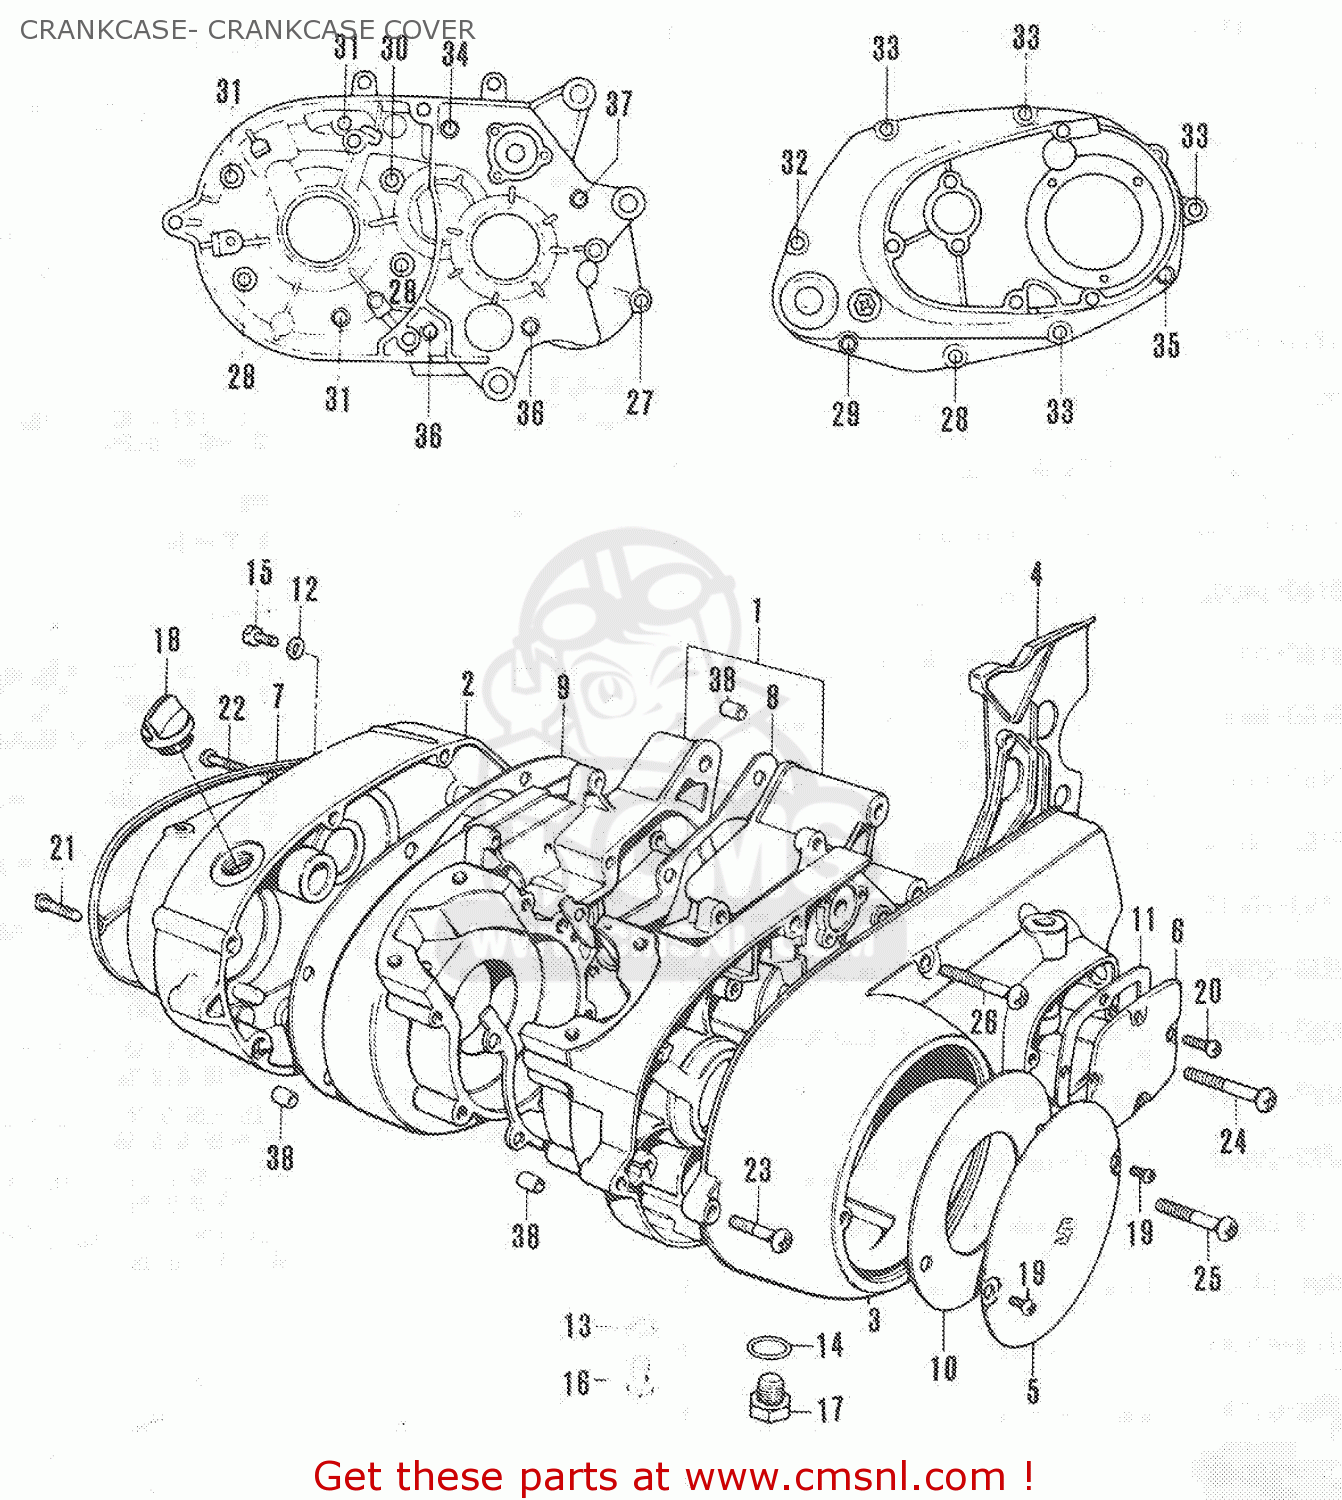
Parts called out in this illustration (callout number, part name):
1	CRANKCASE SET
2	COVER,CLUTCH
3	COVER,MAGNETO
4	COVER
5	CAP,MAGNETO INSPECTION
6	DUCT,BELT COOLING,FRONT
7	COVER,OIL PUMP
8	GASKET,CRANKCASE (MCA)
9	GASKET,CLUTCH COVER (MCA)
10	GASKET,OIL PAN
11	GROMMET,STARTING MOTOR
12	GASKET(6.2X11X1) (NAS)
13	GASKET(10X14X3.6) (NAS)
14	GASKET(14X19.2X2) (NAS)
15	PLUG
16	PLUG
17	PLUG
18	PLUG,OIL FILTER
19	CROSS HEAD SCREW
20	SCREW
21	SCREW
22	SCREW
23	SCREW
24	SCREW
25	CROSS HEAD SCREW
26	SCREW
27	SCREW
28	SCREW
29	SCREW (6X35)
30	SCREW (6X45)
31	SCREW
32	SCREW 6X60
33	SCREW 6X65
34	SCREW 6X70
35	CROSS SCREW (6 X 75)
36	SCREW 6X80
37	SCREW 6X85
38	PIN
